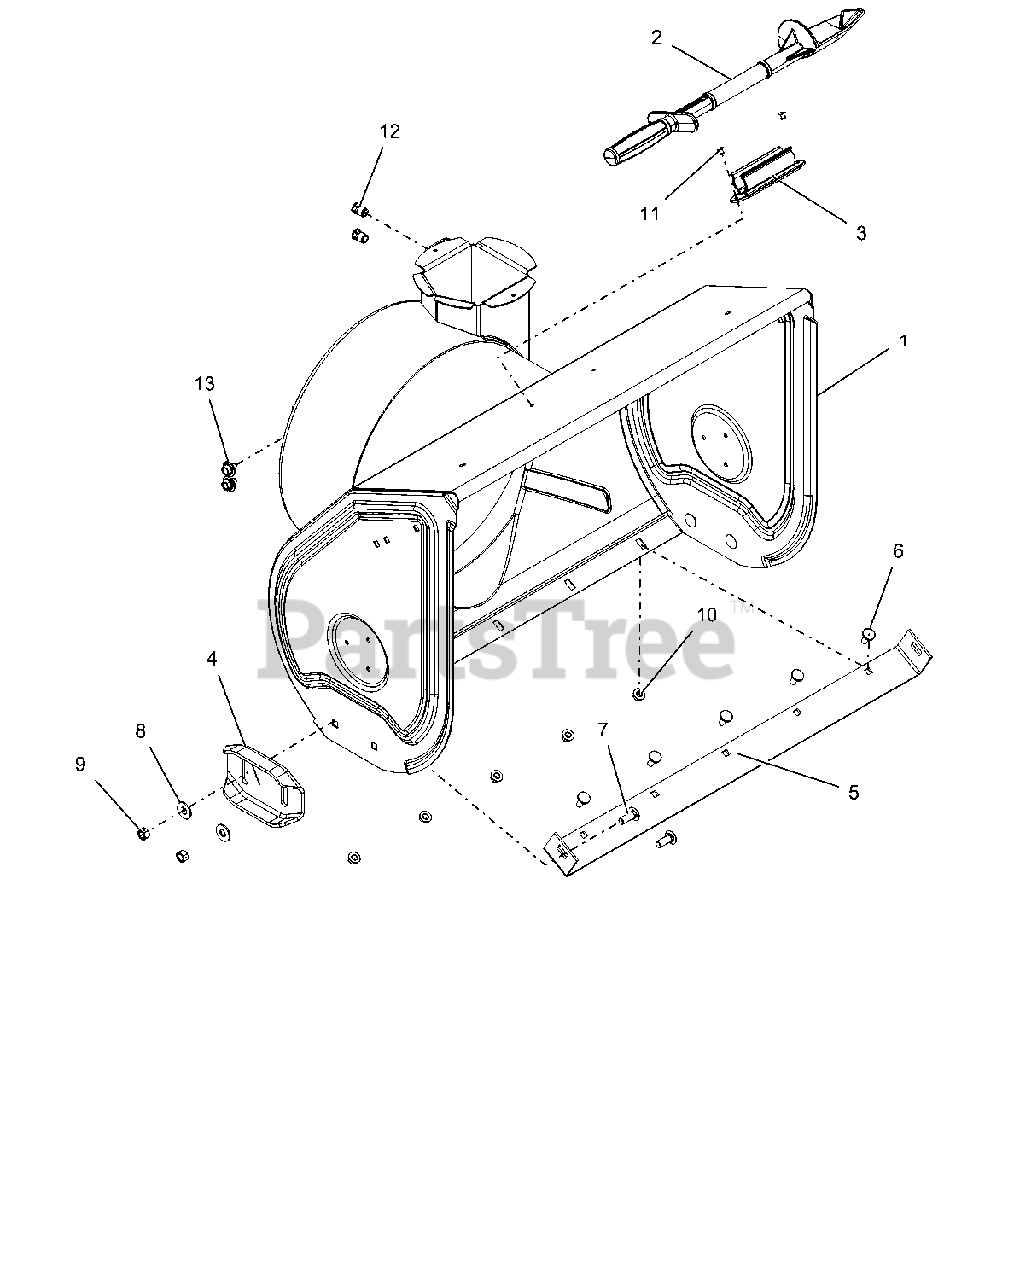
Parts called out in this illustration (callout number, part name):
1	BLOWER HOUSING, 28"
2	DEVICE, SNOW CLEAN OUT
3	MOUNT, SNOW CLEAN OUT
4	SKID SHOE, REVERSIBLE - ORANGE
5	BLADE, SCRAPER - 28"
6	BOLT, MODIFIED HEAD CARRIAGE
7	@BLT-RDHDSHSQNK.38-16X1.0 G5YZ
8	@WSHR-FL-STL.438X1.00X.083 YWZ
9	@NUT-LK-CTR .38-16 YWZC
10	@NUT-LK-TOP-FLG .31-18 YWZC
11	RVT-POP .187 YZ
12	NUT, THREADED INSERT .38-16
13	SCR-TAP.31-18X.50 HWH TR YWZ
